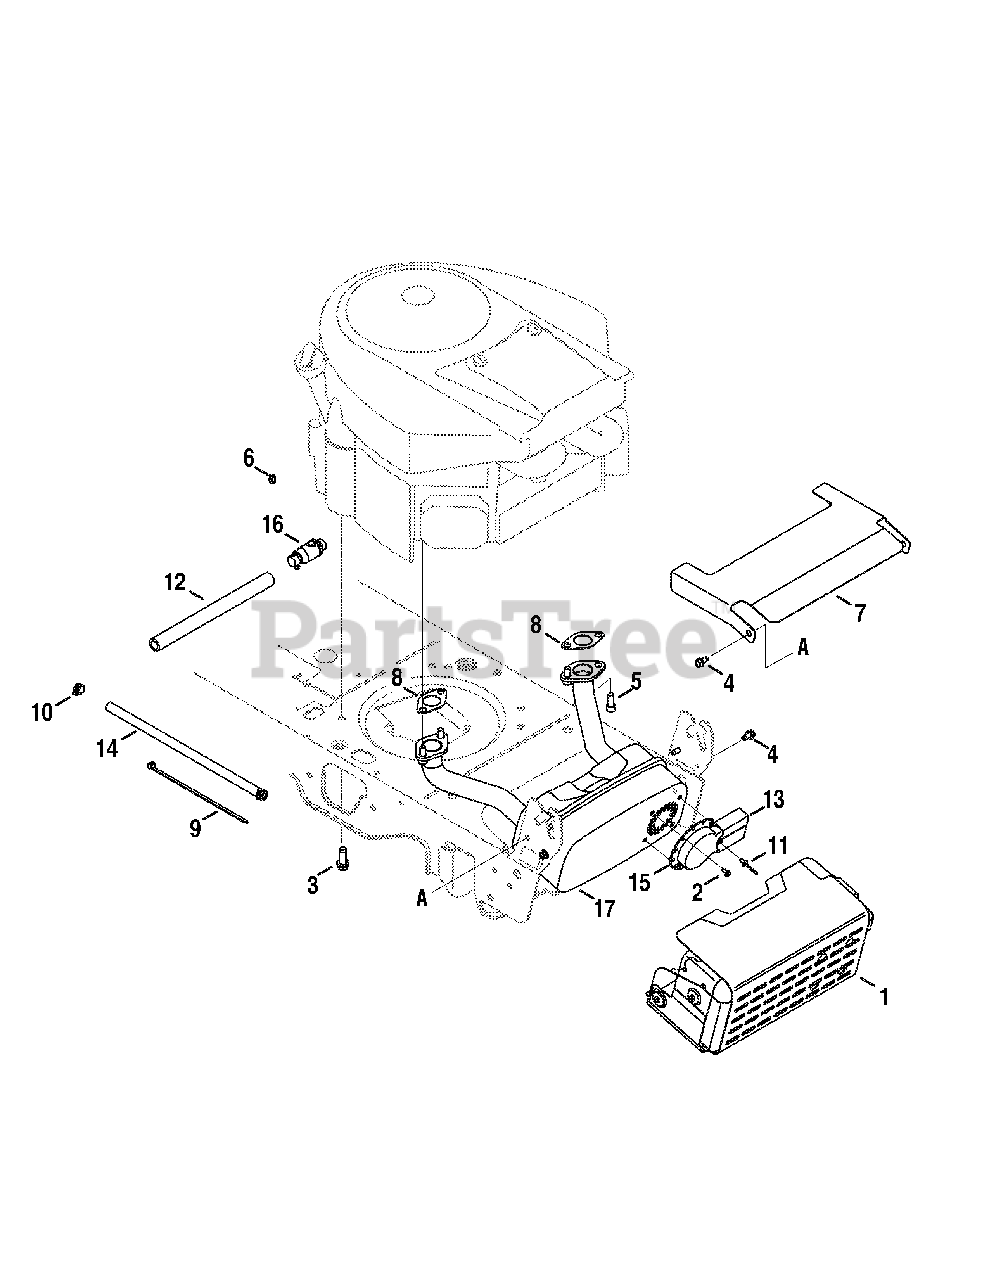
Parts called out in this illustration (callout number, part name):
1	Mulffler Shield Assembly
2	Screw, Indented Washer, #8-18:0.500
3	Taptite Screw, Indented Washer, 3/8-16:1.000
4	Taptite Screw, Indented Washer, 1/4-20:0.500
5	Socket Head Screw, 5/16-18:.750
6	Sems Nut, 1/4-20
7	Heat Shield
8	Exhaust Gasket
9	Cable Tie, 3/16 X .05 X 7.4
10	Hose Clamp, .490 DIA.
11	Rivet, .188 DIA X .300 L
12	Oil Drain Extension Hose
13	Muffler Deflector
14	Fuel Hose
15	Long Muffler Deflector
16	Oil Drain
17	Muffler Deflector
